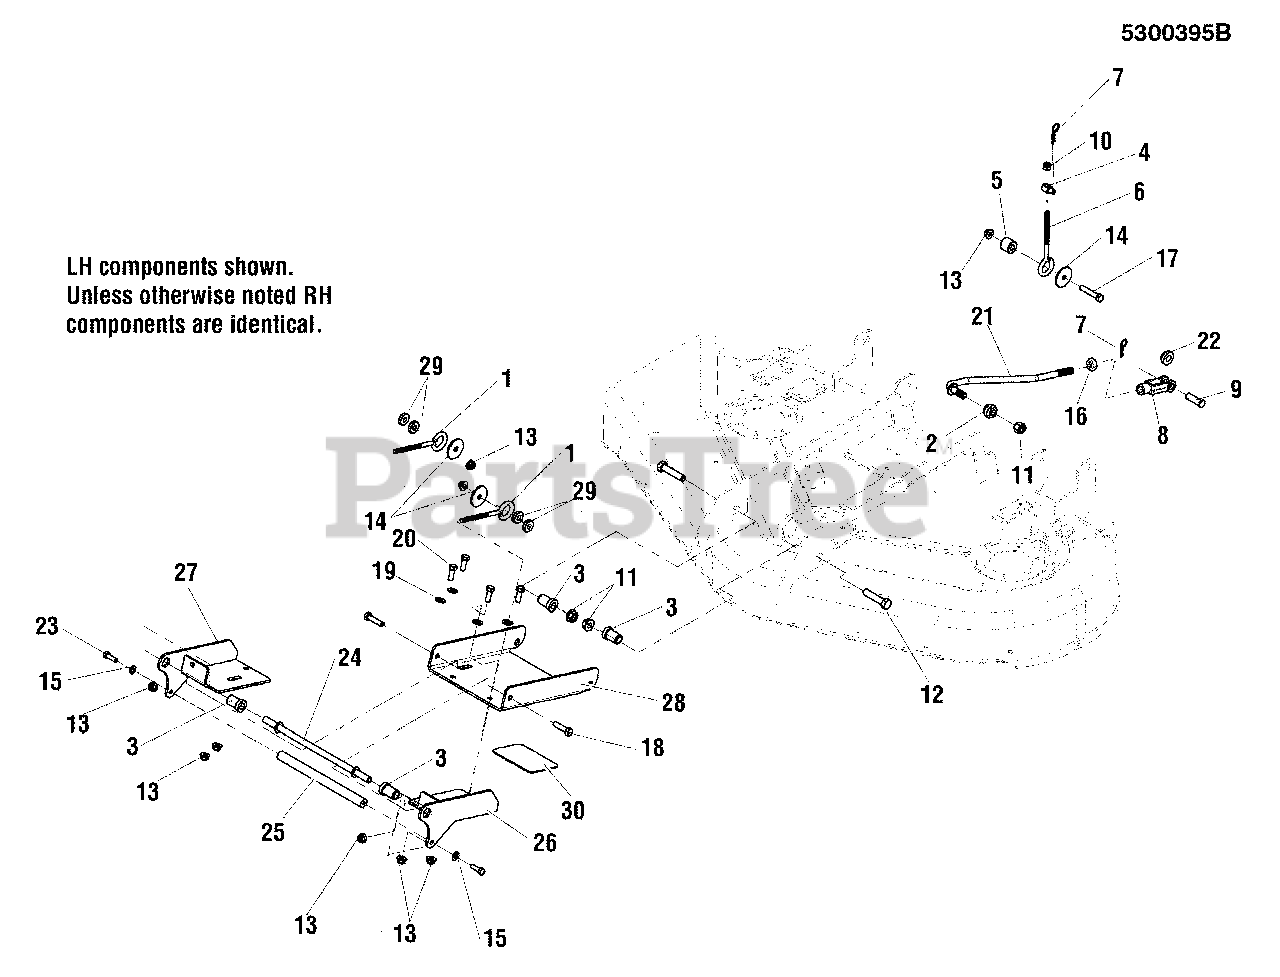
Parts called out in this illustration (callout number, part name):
1	EYE BOLT, 3/8-16 X 5, 1 EYE
2	BUSHING, REAR QUICK TACH, CZ
3	SPACER, .53 X 1.00 X 1.44, CZ
4	ADJUSTER, BRAKE LINKAGE
5	SPACER-0.390ID 0.90 OD 0.70LG P'MTL
6	EYE BOLT, 3/8-16 X 6, 3.0 THREAD
7	PIN, HAIR, .0915 X 1-7/8
8	CLEVIS, 1/2-20, STEEL, CLEAR ZINC
9	PIN, CLEVIS, 1/2 X 1 1/2, YZP
10	NUT, 3/8-16 HEX NYLON LOCK
11	NUT, 1/2-20 HEX NYLON LOCK
12	BOLT, 1/2-20 X 2-1/4 GD8 YZ
13	NUT, 3/8-16 HEX NYLOCK FLANGE
14	WASHER, .41 X 1.75 X .14
15	WASHER, 5/16 LOCK YZ
16	NUT, 1/2-20 HEX JAM
17	BOLT, 3/8-16 X 1-3/4 GD5
18	BOLT, 3/8-16 X 1-1/4 GD5
19	WASHER, 3/8 SAE
20	BOLT, 3/8-16 X 1 GD5 YZ
21	ROD, DECK LIFT LINKAGE
22	BUSHING, DECK SUPPORT
23	BOLT, 5/16-18 X 1 GD5 YZ
24	SHAFT, HANGER
25	SHAFT, HANDLE, DECK MOUNT
26	WELD, DECK HANGER, LH - ORG
27	WELD, DECK HANGER, RH - ORG
28	PLATE, DECK HANGER SUPPORT - ORG
29	SPACER, .39 X 1.00 X .25
30	SAFETY WALK, 4.50 X 3.50
